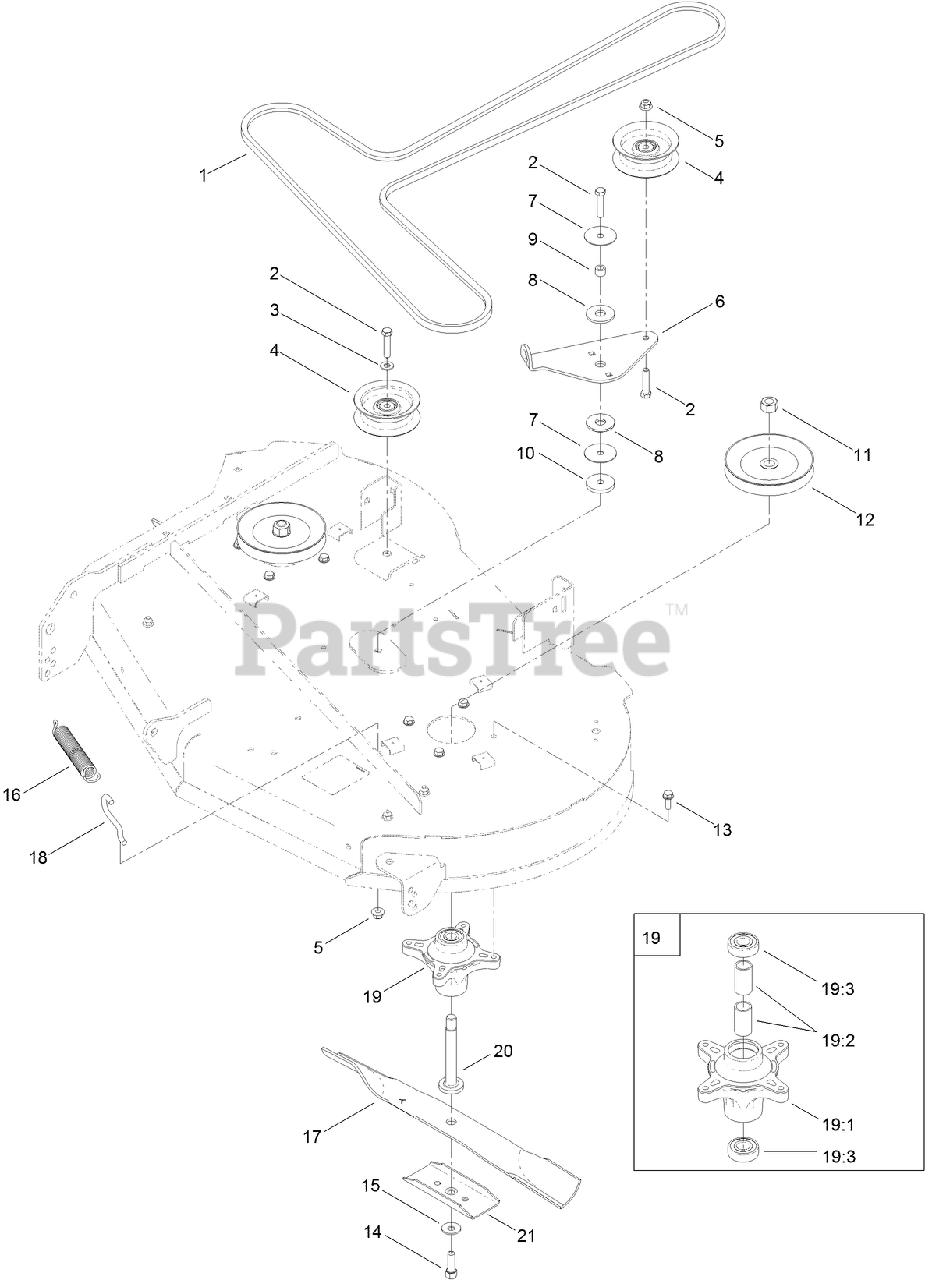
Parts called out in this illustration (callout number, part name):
1	V-BELT
2	SCREW-HH
3	WASHER-FLAT
5	NUT-HF, NI
6	ARM-IDLER
7	WASHER
8	WASHER-FRICTION, COMPOSITE
9	SPACER
10	SCREW-HH
11	NUT-HEX
12	PULLEY
13	SCREW-TAPTITE
14	SCREW-HH
15	WASHER-BELLEVILLE
16	SPRING-EXTENSION
17	BLADE-21.6 INCH
18	HOOK-RETURN, SPRING
19	SPINDLE ASM
19:2	SPACER
20	SHAFT-SPINDLE
21	STIFFENER-BLADE
